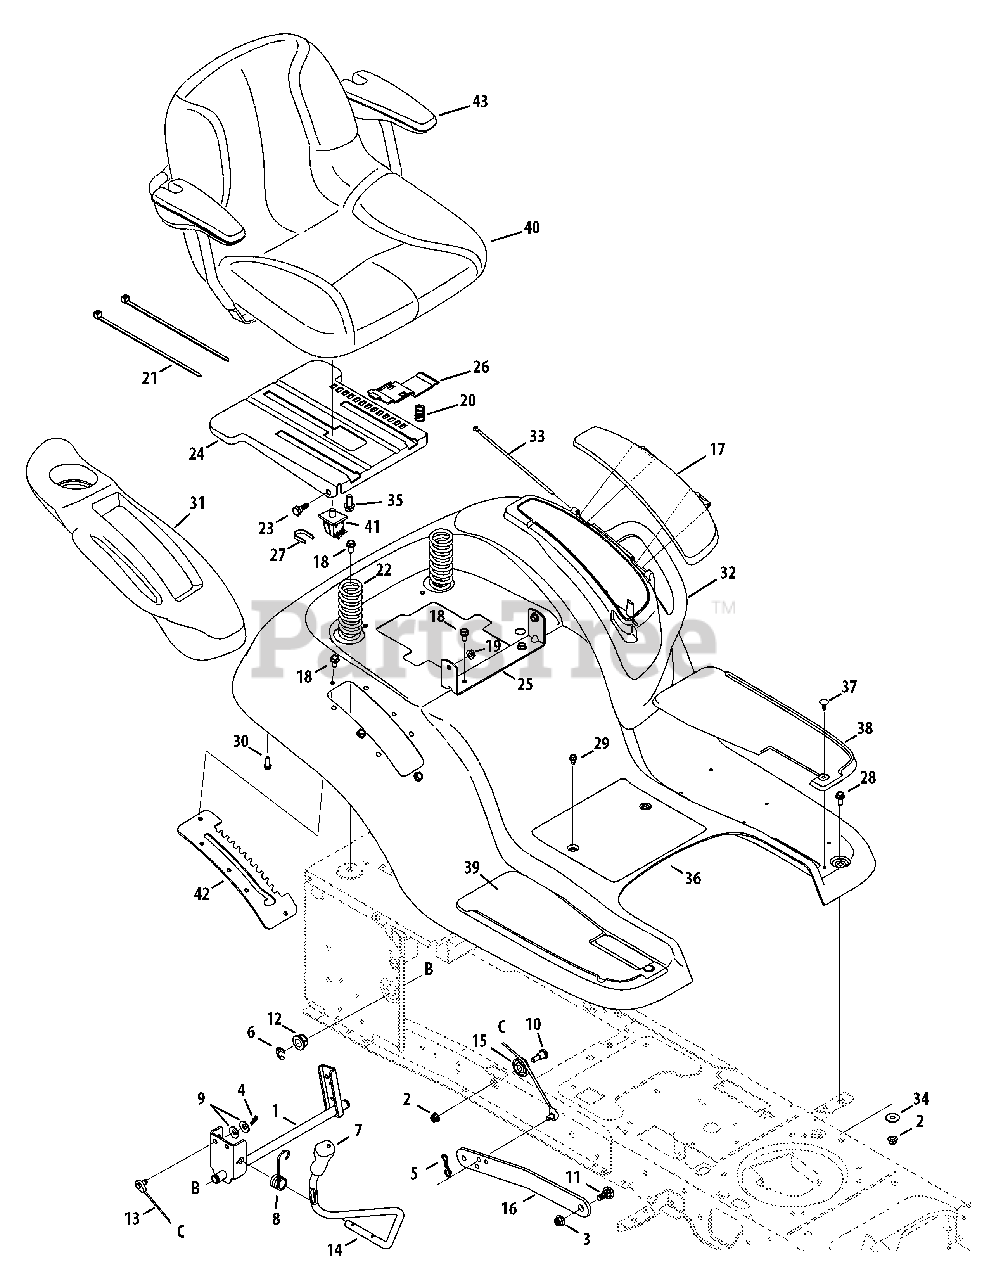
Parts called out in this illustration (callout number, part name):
1	Shaft Ass’y, Lift, 50"
2	Nut, Flange Lock, 5/16-18, Grf
3	Nut, Flange Lock, 3/8-16, Grf
4	Pin, Cotter, .072 Dia. x 1.13
5	Pin, Cotter, Bow-Tie 72
6	Ring, E Type, .625 Dia. Shaft
7	Grip, Handle, Cub, .50 ID
8	Spring, Torsion
9	Washer, Spring, .401 x .870 x .063
10	Screw, Shoulder, .437 x .470, 5/16-18
11	Bolt, Shoulder, .50, 3/8-16
12	Bearing, Hex Flange
13	Cable, Lift, 16.64, 50"
14	Handle, Lift,
15	Pulley, Roller, Cable
17	Door, Cover, Fender
18	Screw, Self-tapping, 5/16-18, .750,
19	Nut, Flange Lock, 5/16-18, Gr5, Sd Lk
20	Spring, Compr’, .68 x 1.065 x .055
21	Cable, Tie, 3/16 x .05 x 7.4
22	Spring, Comprs, 1.50 x 3.90 x .200
23	Screw, Shoulder, .437 x .268, 5/16-18
24	Bracket, Mounting, Seat
25	Bracket, Pivot, Seat
26	Lever, Seat Adjustment
27	Clip, Retaining, Switch
28	Hex Screw, 5/16-18, .75, Gr5, Std
29	Screw, Self-tapping, 1/4-20, 0.500,
30	Screw, HL, 1/4-15, 0.750,
31	Cover, Fender, RH
32	Cover, Fender, LH
34	Washer, Flat .344 x 1.00 x .063
35	Hex Flange Bolt, 3/8/16, .875, Gr5
36	Fender, Cub Hydro
37	Clip, Ratchet, .250 Dia
38	Pad, Foot, LH
39	Pad, Foot, RH
40	Seat, High Back Cloth w/o Arm Rest
41	Switch, Seat
42	Bracket, Lift
43	Arm Rest Kit
